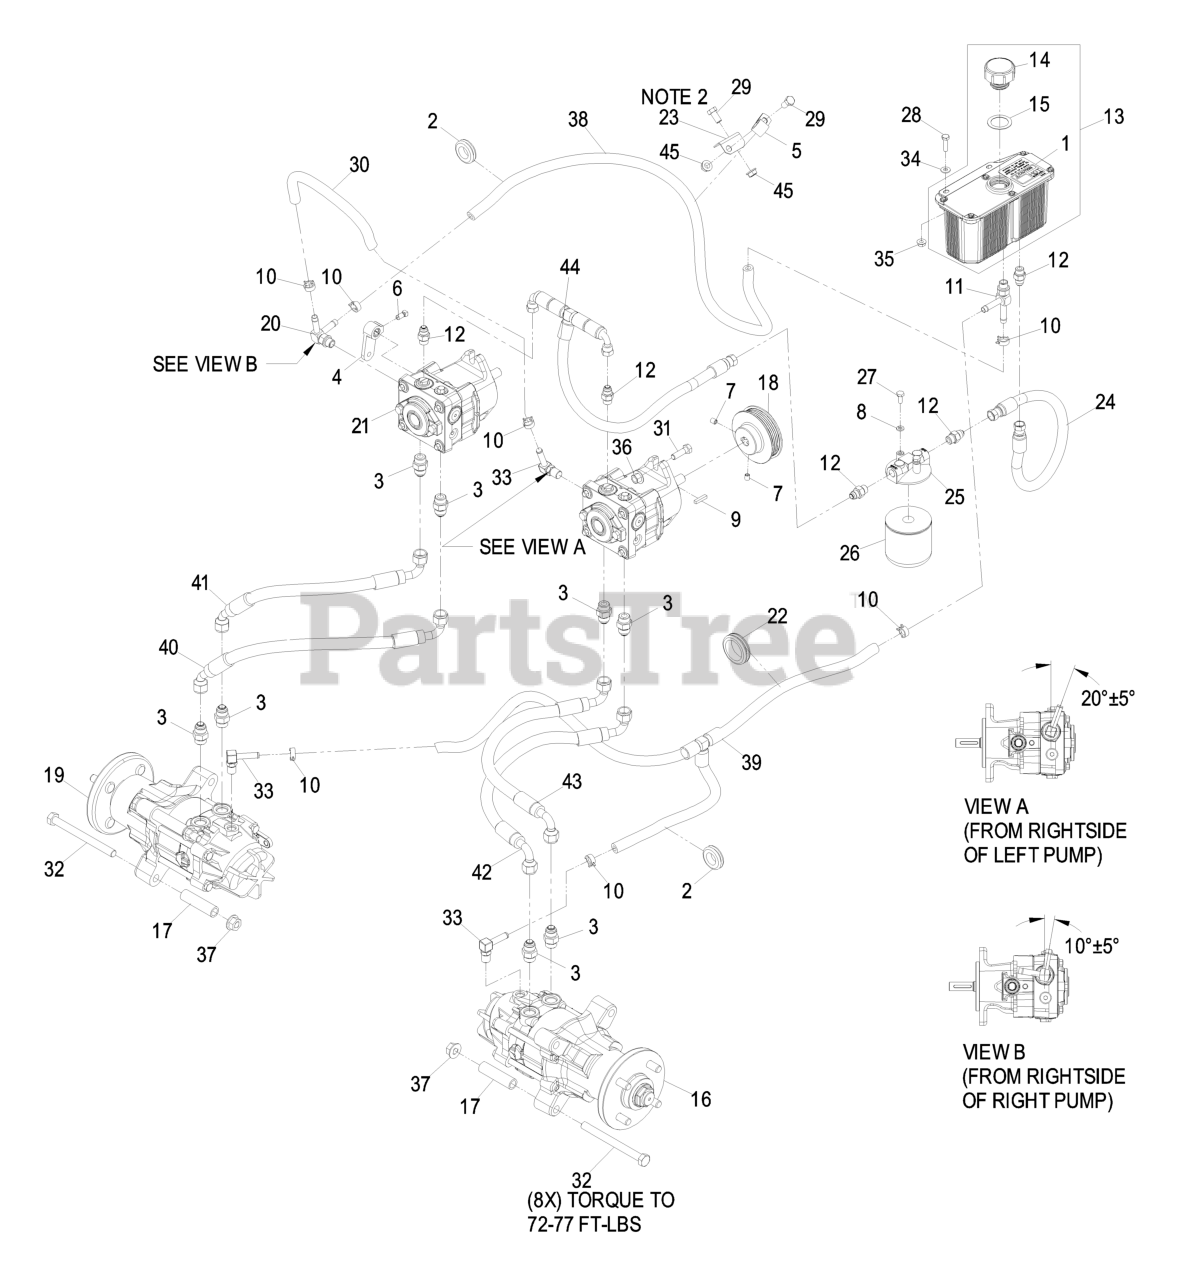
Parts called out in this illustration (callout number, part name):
2	GROMMET
3	FITTING-STRAIGHT
4	ARM-CONTROL, PUMP
5	CLIP-LOOM
6	SCREW-SET
7	SCREW-SET
8	WASHER-LOCK
10	CLAMP-HOSE
11	ADAPTER-RUN, TEE
12	FITTING-STRAIGHT
13	HYD RESERVOIR ASM
14	Cap-Reservoir, HYD
15	GASKET-CAP
16	MOTOR,PRM18-LH
19	MOTOR,PRM18-RH
20	ADAPTER-TEE
22	GROMMET
23	BRACKET-CLAMP
24	HYDRAULIC HOSE ASM
25	HEAD-FILTER
26	Element, Filter 25 Micron
27	SCREW-HH
28	SCREW-HH
29	SCREW-HH
30	HOSE-HYD
31	SCREW-HH
32	SCREW-HH
33	FITTING-ELBOW, 90
34	WASHER-FLAT
36	NUT-FLANGE
37	NUT-HHF
38	HOSE-HYD
39	ASM,HYDRAULIC HOSE
40	ASM,HYDRAULIC HOSE
41	ASM,HYDRAULIC HOSE
42	ASM,HYDRAULIC HOSE
43	ASM,HYDRAULIC HOSE
44	HYDRAULIC HOSE ASM
45	NUT-HHF, WHIZ
